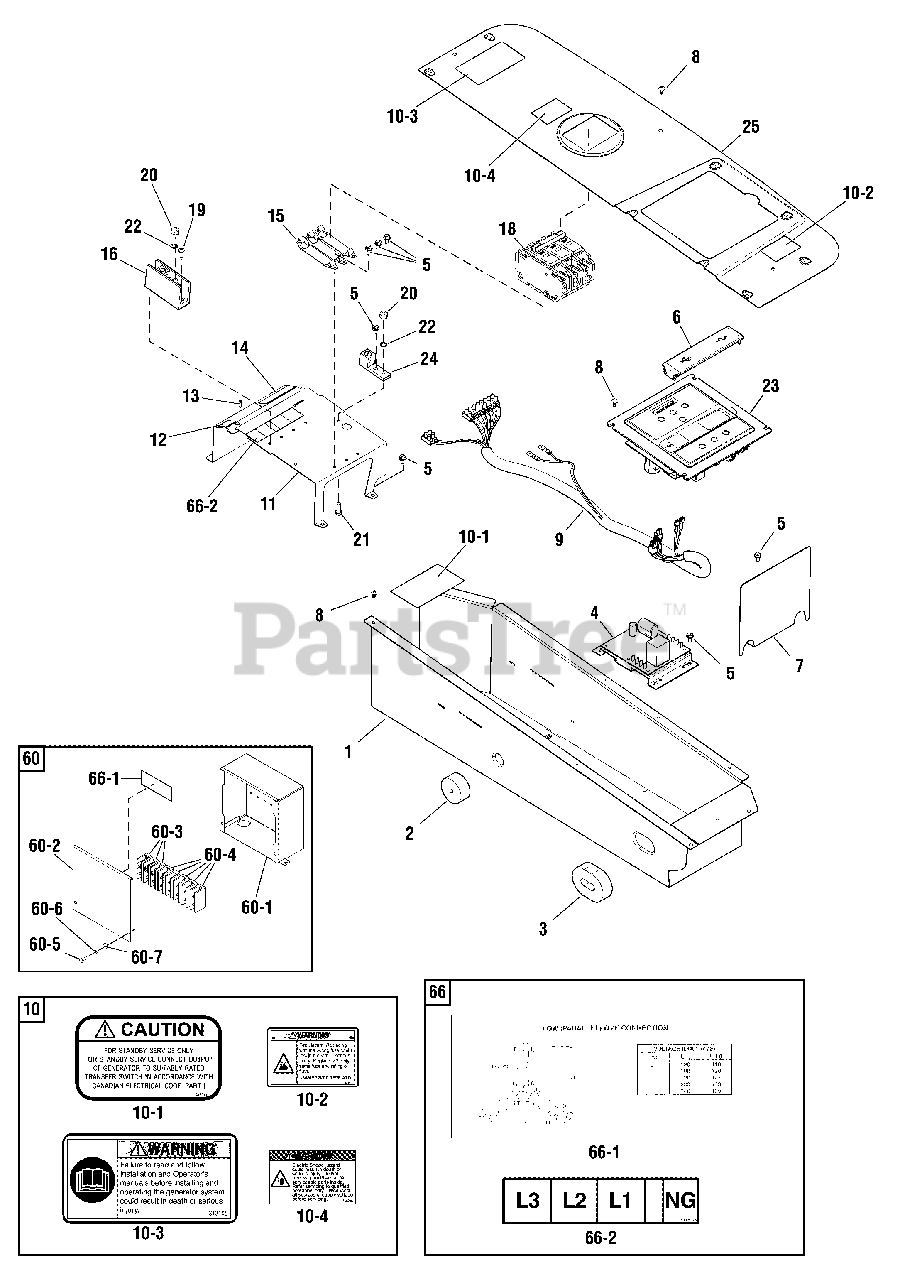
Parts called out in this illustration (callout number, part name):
4	REGULATOR, Voltage
5	* BOLT, Hex Head, #10-32 x 3/8
8	* SCREW, #10-32 x 3/8
10	DECAL SHEET, Warnings
10-1	DECAL, Caution
10-2	DECAL, Warning Fire Hazard
10-3	DECAL, Warning Read Manual
10-4	DECAL, Warning, Electric Shock
13	* SCREW, M2.5-0.45 x 8
18	BREAKER, Circuit
19	* SCREW, #10-32 x 3/4
20	* NUT, 1/4-20
21	* CAPSCREW, Hex Head, 1/4-20 x 3/4
22	* WASHER, External Lock, M6
23	CONTROL PANEL
25	COVER, Control Panel Box
60	TERMINATION BOX
60-2	COVER
60-5	* CAPSCREW, Hex Head, 1/4-20 x 3/4
60-6	* WASHER, Lock, 1/4
60-7	* WASHER, Flat, 1/4
66	DECAL SHEET-VOLTAGE
66-1	DECAL, Voltage
66-2	DECAL, Line/Neutral
